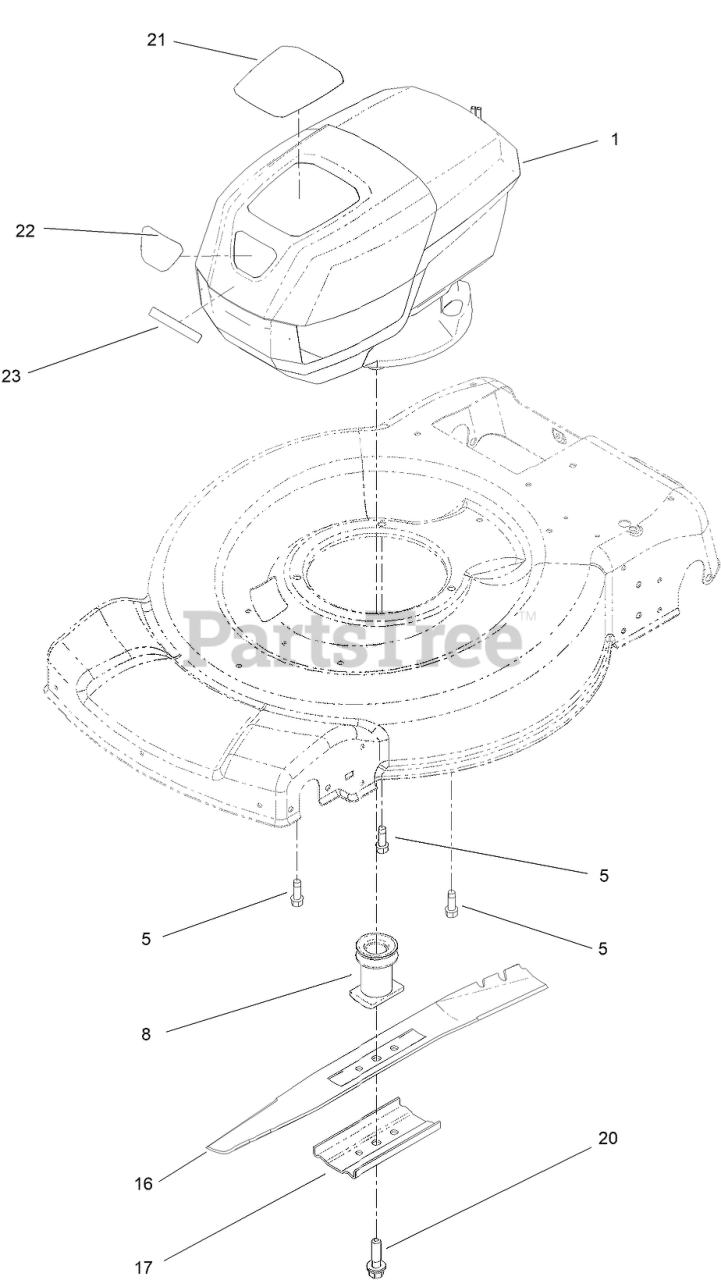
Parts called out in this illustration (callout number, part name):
1	MOTOR MODULE 60V
5	SCREW-THD FORM, HWH
8	DRIVER-BLADE
16	BLADE [BLACK]
17	SUPPORT-BLADE
20	BOLT-BLADE
